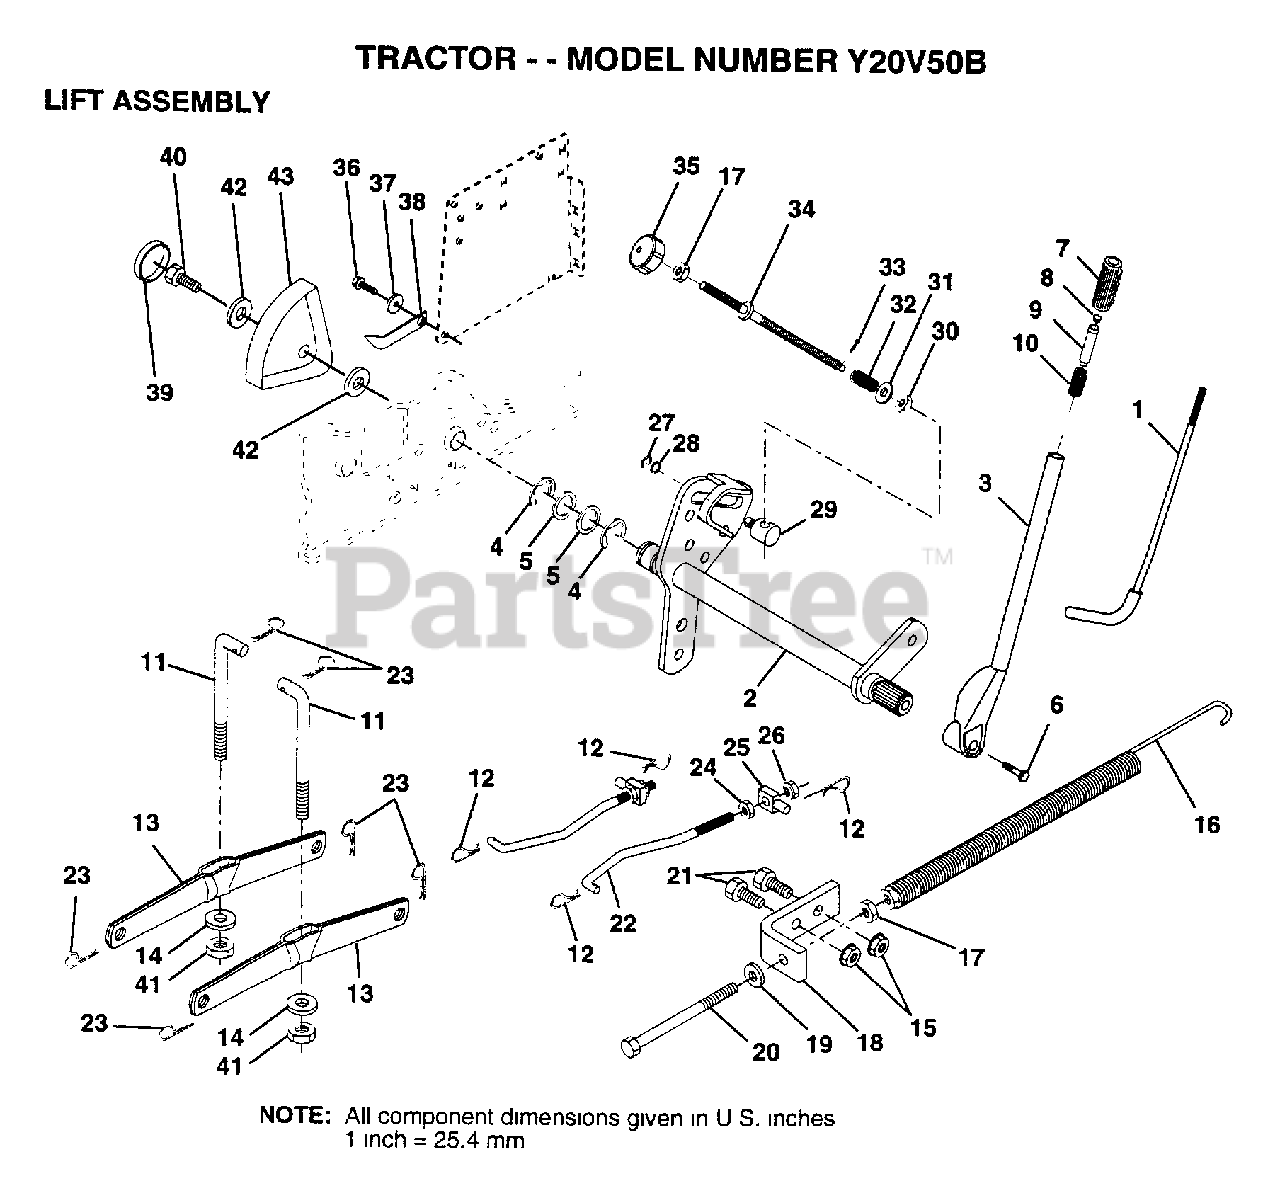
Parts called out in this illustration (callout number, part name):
1	LEVER ROD LT
2	SHAFT.LIFT.VGT.95
4	E-RING
5	WASHER
6	"BOLT,HEX"
7	GRIP HANDLE
10	SPRING T
11	LINK.ASM.MWR.VGT
12	RETAINER.SPRING
13	ARM SUSP REAR
14	BEARING PVT LH
17	NUT
18	BRACKET SPRING AS
19	WASHER
20	BOLT-ADJ SPRING T
21	BOLT
22	LINK.FRONT
24	NUT
25	TRUNION
26	NUT.LK.W/WSH.1/2.
27	KLIP RING
28	WASHER
29	TRUNION LT
30	NUT T
31	WASHER
32	SPRING.COMP.INF.H
34	ROD.ADJ.LIFT
35	KNOB INF 3/8-16
36	SCREW
37	WASHER T
39	"PLUG,HOLE"
40	SCREW
41	NUT.CROWNLOCK.3/8
42	WASHER
43	HEIGHT INDICATOR
